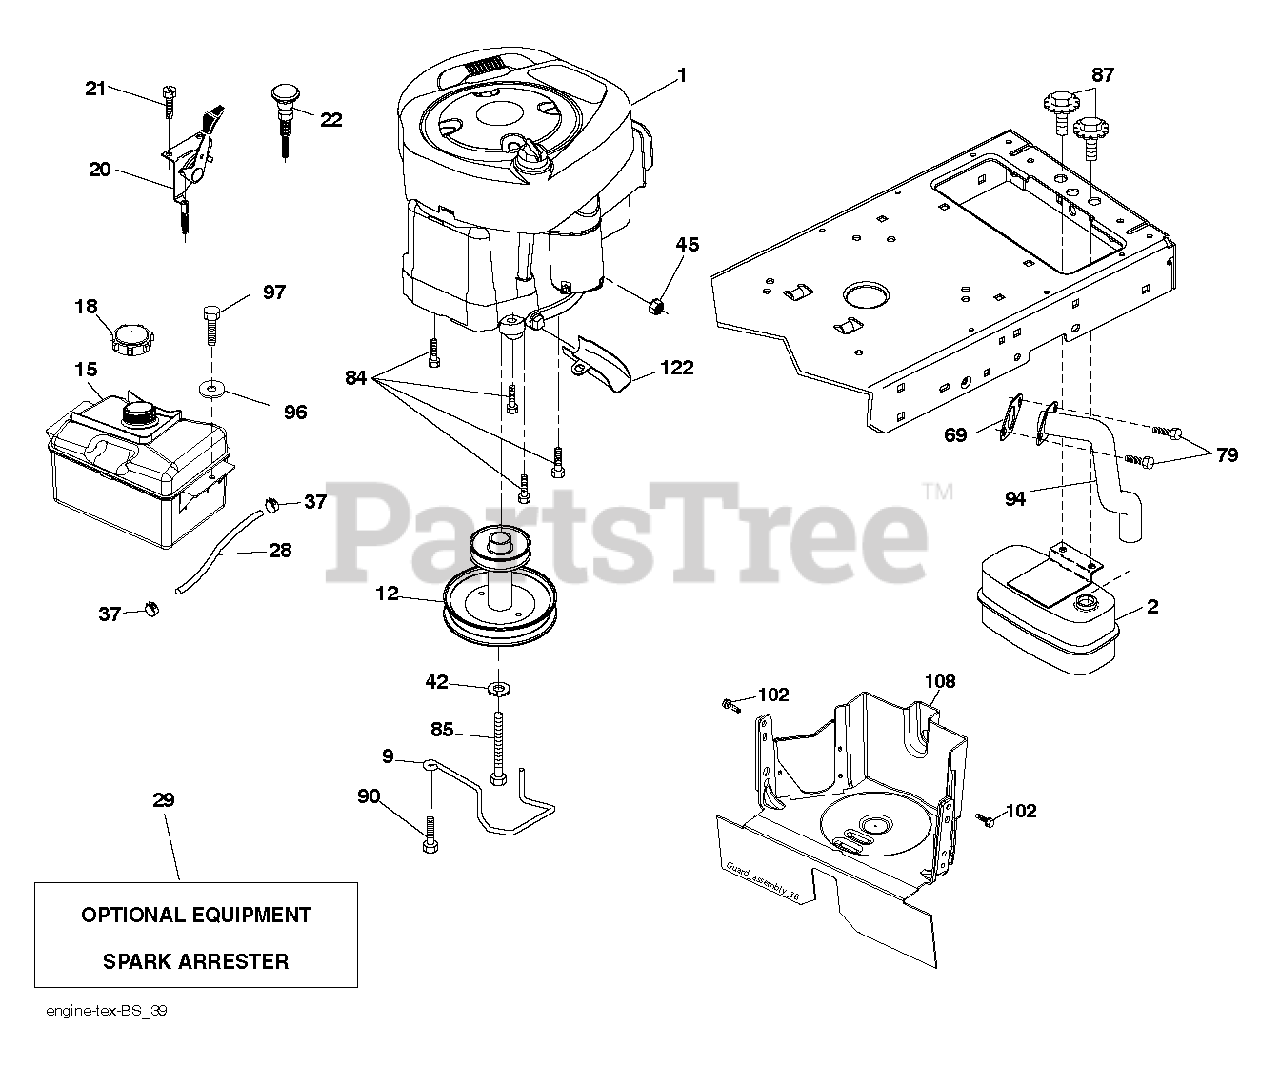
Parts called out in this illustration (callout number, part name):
2	Muffler, Single Cylinder Kohler/B&S
9	KEEPER.BELT.ENGINE.4.2
12	PULLY ENGINE
18	CAP ASM.FUEL.2.25"FR.
20	CONTROL.TH/CK.C.
21	SCREW.#10 X 0.750.BOS THREAD
28	LINE.FUEL.20
29	ARRESTER SPARK (OPTIONAL)
37	HOSE CLAMP
42	LOCKWASHER
45	NUT
69	REPL BY 532 27 22-93
79	SCREW.SOCKET HD.5/16-1
84	SCREW.3/8-16
85	BOLT HEX 7/16-20X4-1/4"
87	BOLT, 5/16-18 X 1 3/4
90	SCREW 3/8-16X1
94	Exhaust Tube, B&S 28/31
97	SCREW HEXWSHR 1/4-20X3/4
102	SCREW 5/16-18X1
122	EXTENSION DRAIN OIL
